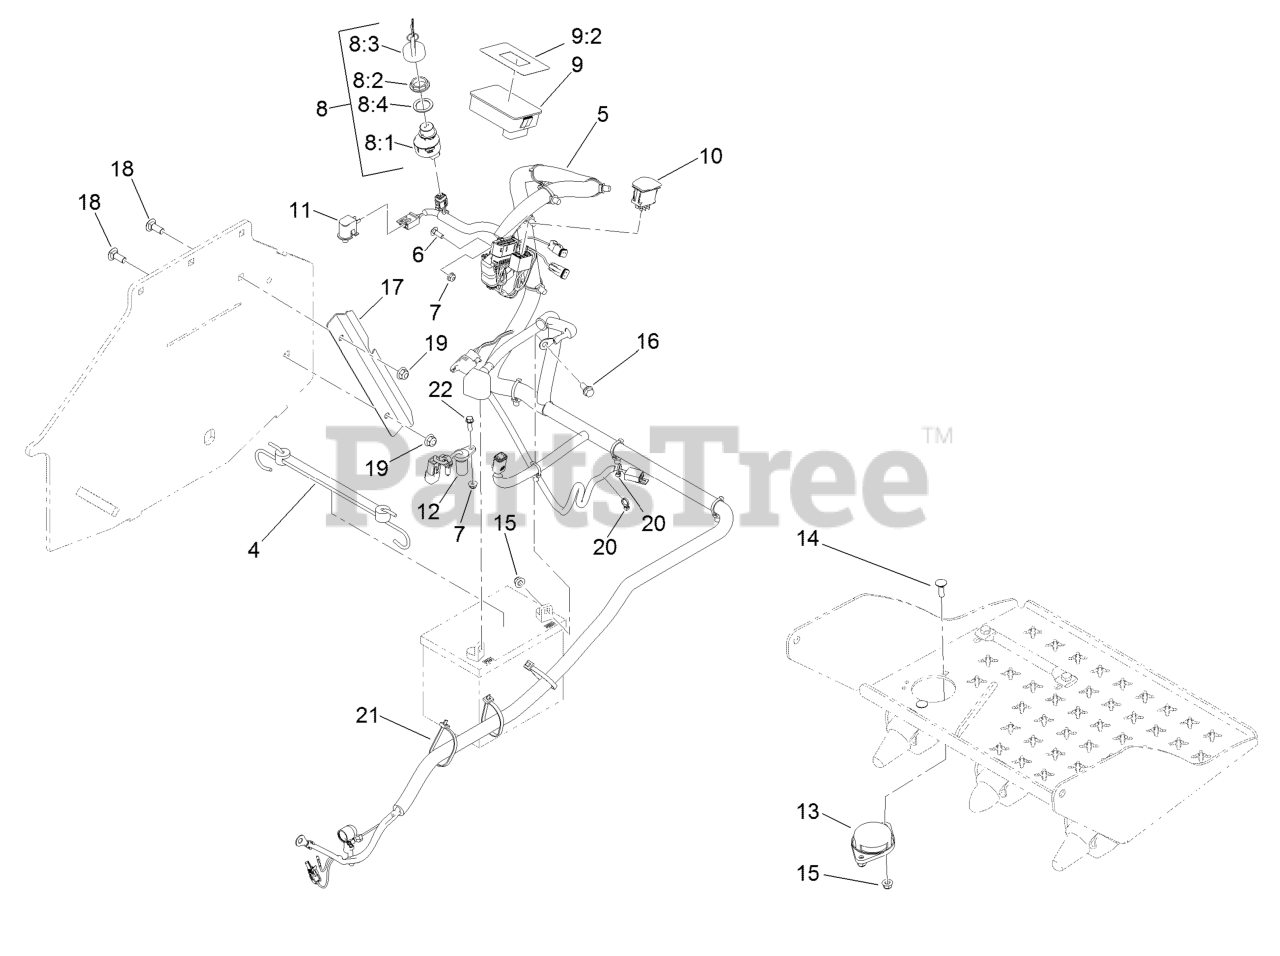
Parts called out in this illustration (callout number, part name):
4	Holddown-Battery
5	Harness-Wire
6	Bolt-CARR
8	Ignition Switch ASM
8:1	Switch-Ignition
8:2	Nut-Mounting
8:3	Ignition Key Set
8:4	Washer-Backup
9	Hour Meter ASM
9:2	Decal-Meter, Hour
10	Switch, (On)-Off-(On)
11	Switch-Bail
12	Sensor-Quadrature
13	Switch-Seat
14	Bolt-CARR
15	Nut-HF, NI
16	Screw-HHF
17	Guard-Harness
18	Bolt-CARR
19	Nut-HF, NI
20	Tie-Cable
21	Tie-Plastic
22	Screw-HWH
